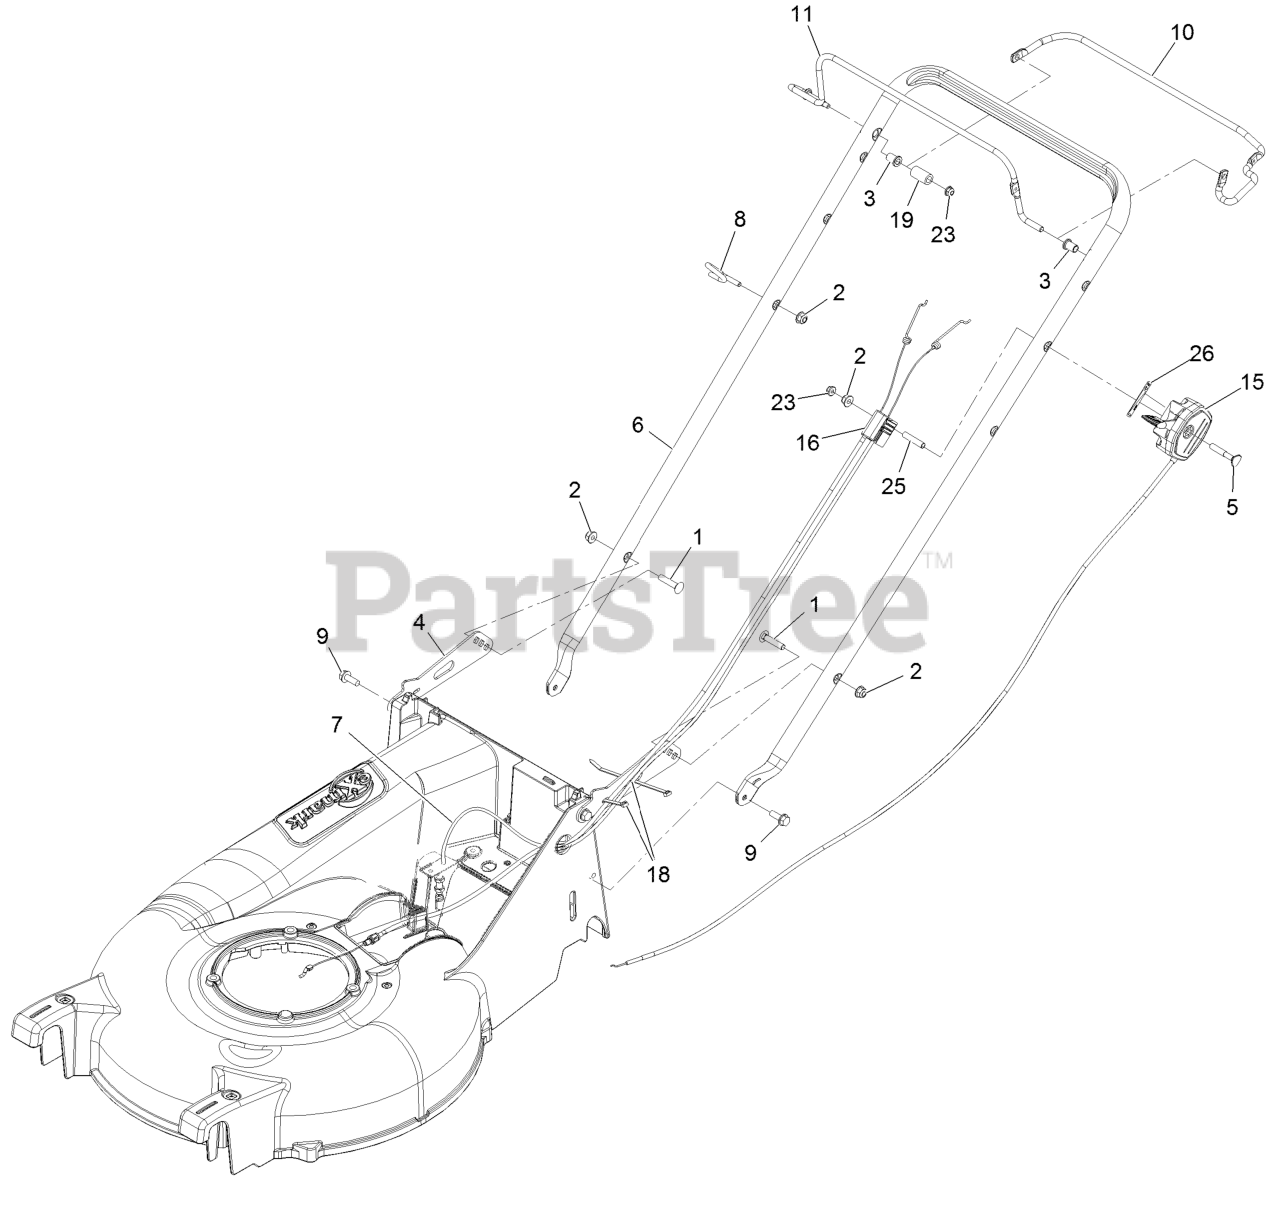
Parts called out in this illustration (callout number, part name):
1	BOLT-CARR
2	NUT-HF, NI
3	BUSHING-HANDLEBAR
4	BRACKET,HANDLEBAR
5	SCREW-HH
6	HANDLEBAR-P21
7	CABLE, DRIVE EC21
8	GUIDE,ROPE
9	SCREW-TAPTITE
10	BAIL-DRIVE COATED
15	CABLE-THROTTLE/CHOKE
16	CABLE-ZONE HONDA
18	TIE-CABLE
25	SPACER-THROTTLE
26	DECAL,THROTTLE/CHOKE
